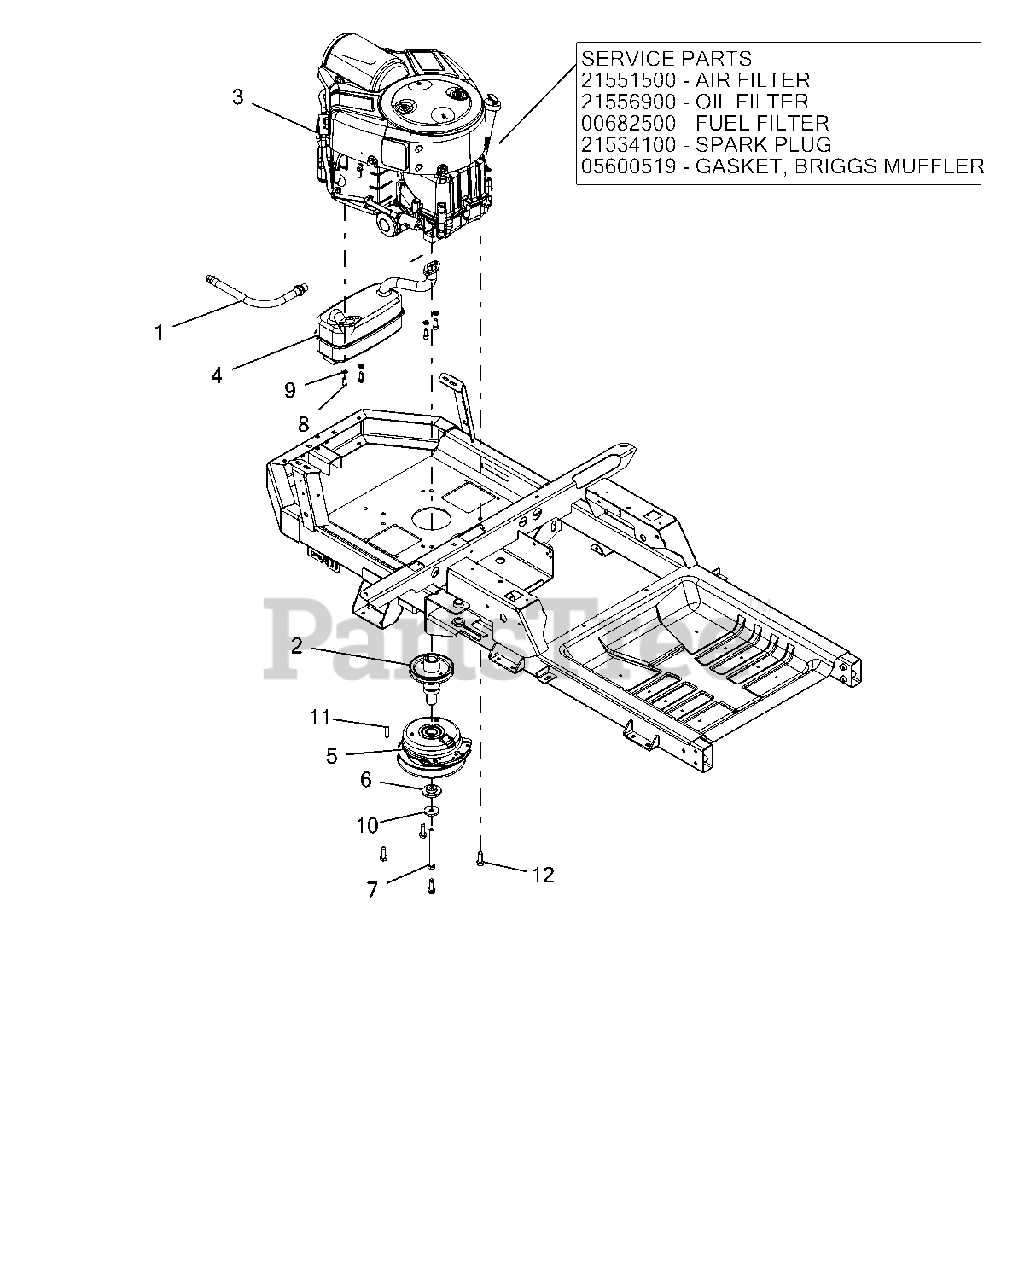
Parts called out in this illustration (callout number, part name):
1	HOSE, OIL DRAIN
2	WLDMT, DRIVE SHEAVE (XL60 LG)
3	PLUG, SPARK
3	ENGINE, B&S 24 HP IKON
3	FILTER, BRIGGS AIR
3	OIL FILTER, BRIGGS
3	GASOLINE FILTER, BRIGGS
3	GASKET, MUFFLER BRIGGS 690970
4	MUFFLER ASSEMBLY
5	CLUTCH,105FTLB MONOPOLE 6.83"
6	BSHG-FLG .469X1.06X.574X2.0
7	BLT-HEX.438-20X4.5GR8YZ NYTORQ
8	SCR-CAP .31-18X.75 S/HD
9	@WSHR-LK .31X.078 REG YWZC
10	WASHER, 7/16" SPRING DISK
11	KEY-SQ .25 X 1.25 X .25 SAE
12	@SCR-TAP .38-16X1.25 HWH TR YZ
